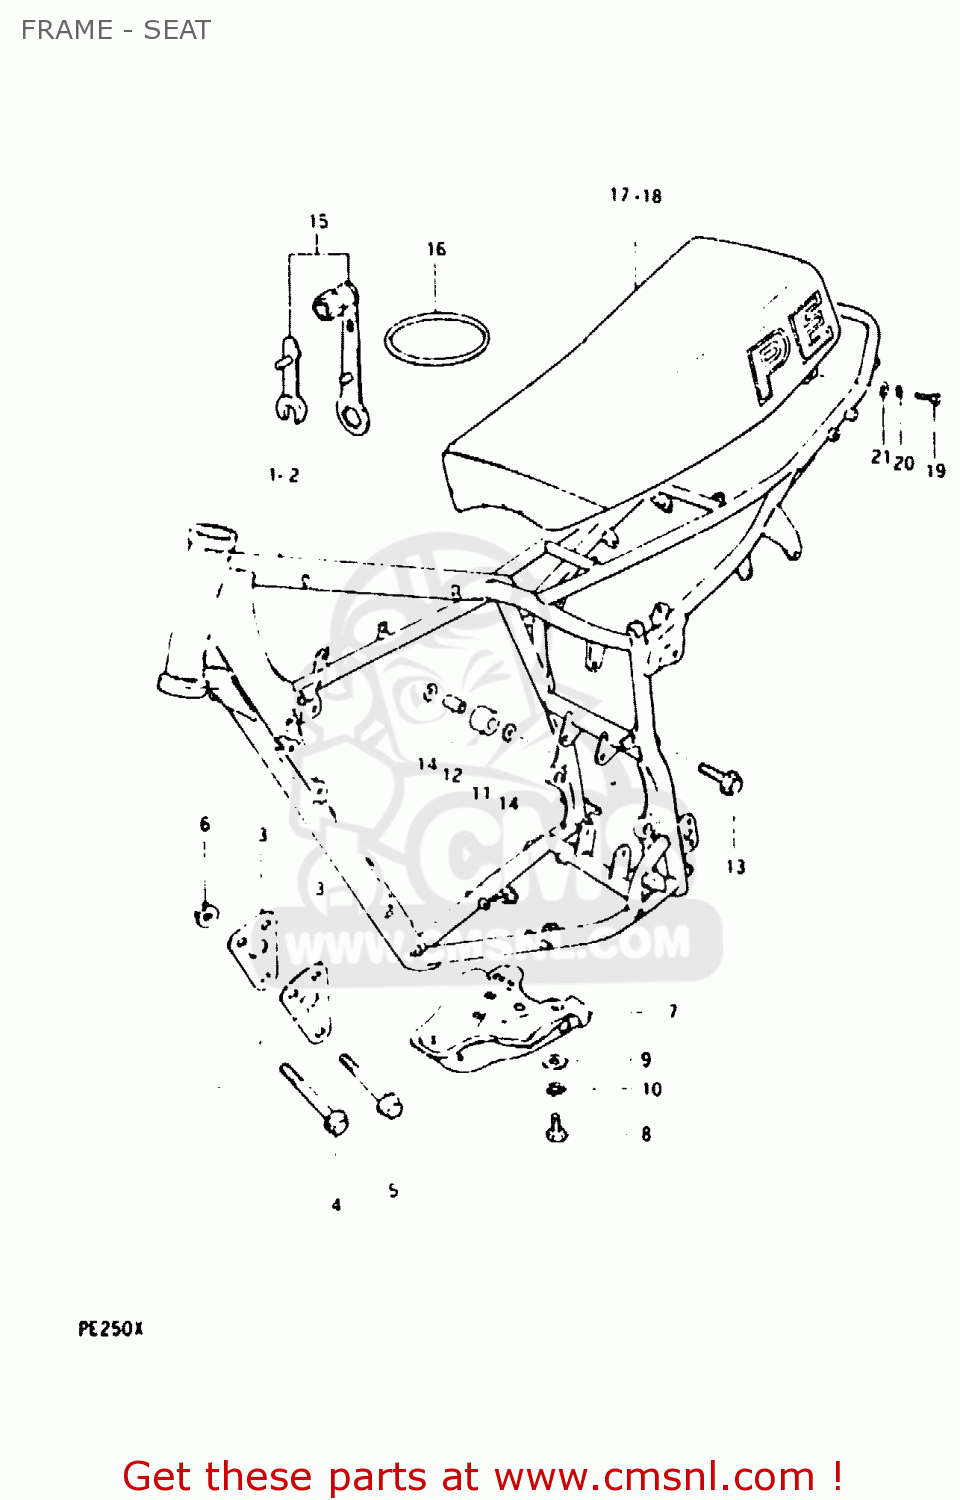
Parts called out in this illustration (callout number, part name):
2	FRAME (BLACK)
3	PLATE,ENGINE MOUNTING
4	BOLT(8X67)
5	BOLT
6	NUT
7	PROTECTOR,ENGINE
8	BOLT
9	WASHER (8.2X20X1.6)
10	LOCK WASHER
11	ROLLER,CHAIN CONTROL
12	SPACER,CHAIN LENGTH ROLLER
13	BOLT(8X45)
14	WASHER
15	SPARK PLUG WRENCH
16	O RING TOOL FITTING
18	SEAT ASSY (BLACK)
19	BOLT
20	LOCK WASHER
21	WASHER (8.2X20X1.6)
